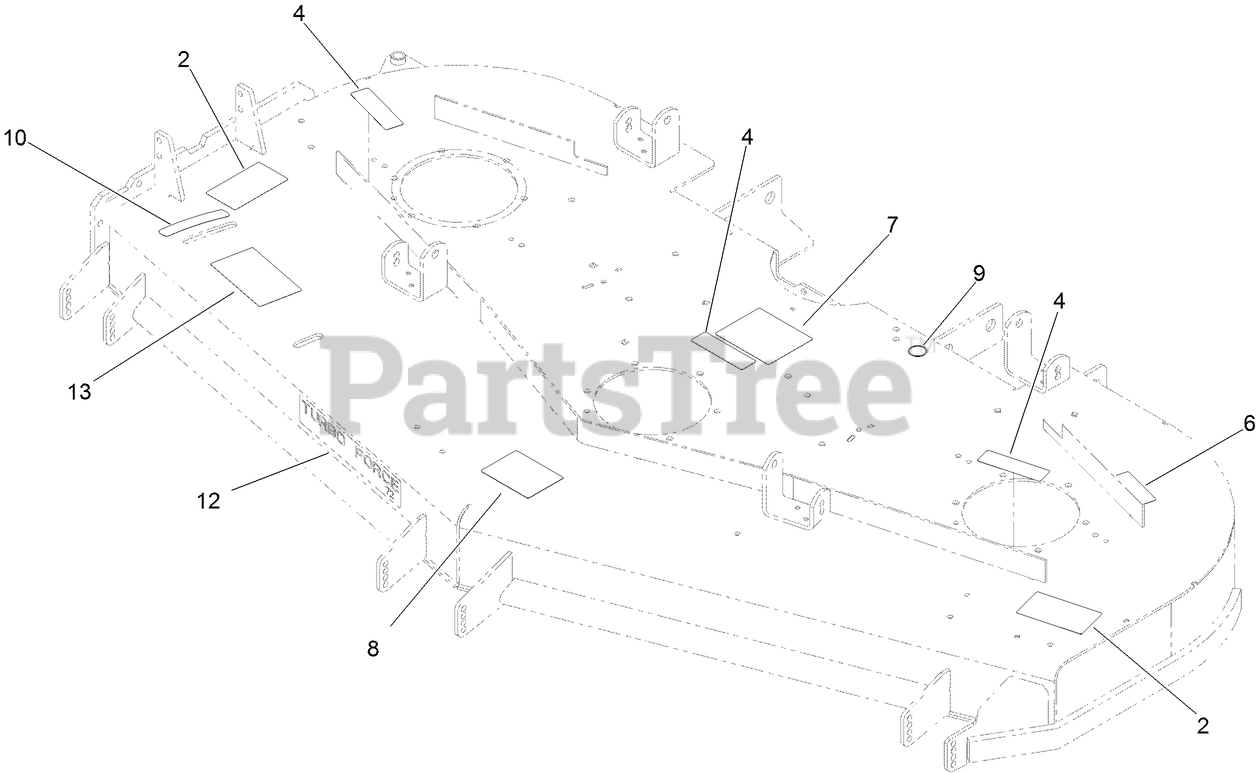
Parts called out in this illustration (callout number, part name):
2	DECAL-DANGER
4	DECAL-COVER, MISSING
6	DECAL-BOLT TORQUE
7	DECAL-ROUTING, BELT
8	DECAL-SCALP, ANTI
9	DECAL-GREASE
10	DECAL-SETTING, BAFFLE
13	DECAL-ADJUSTMENT, BAFFLE
